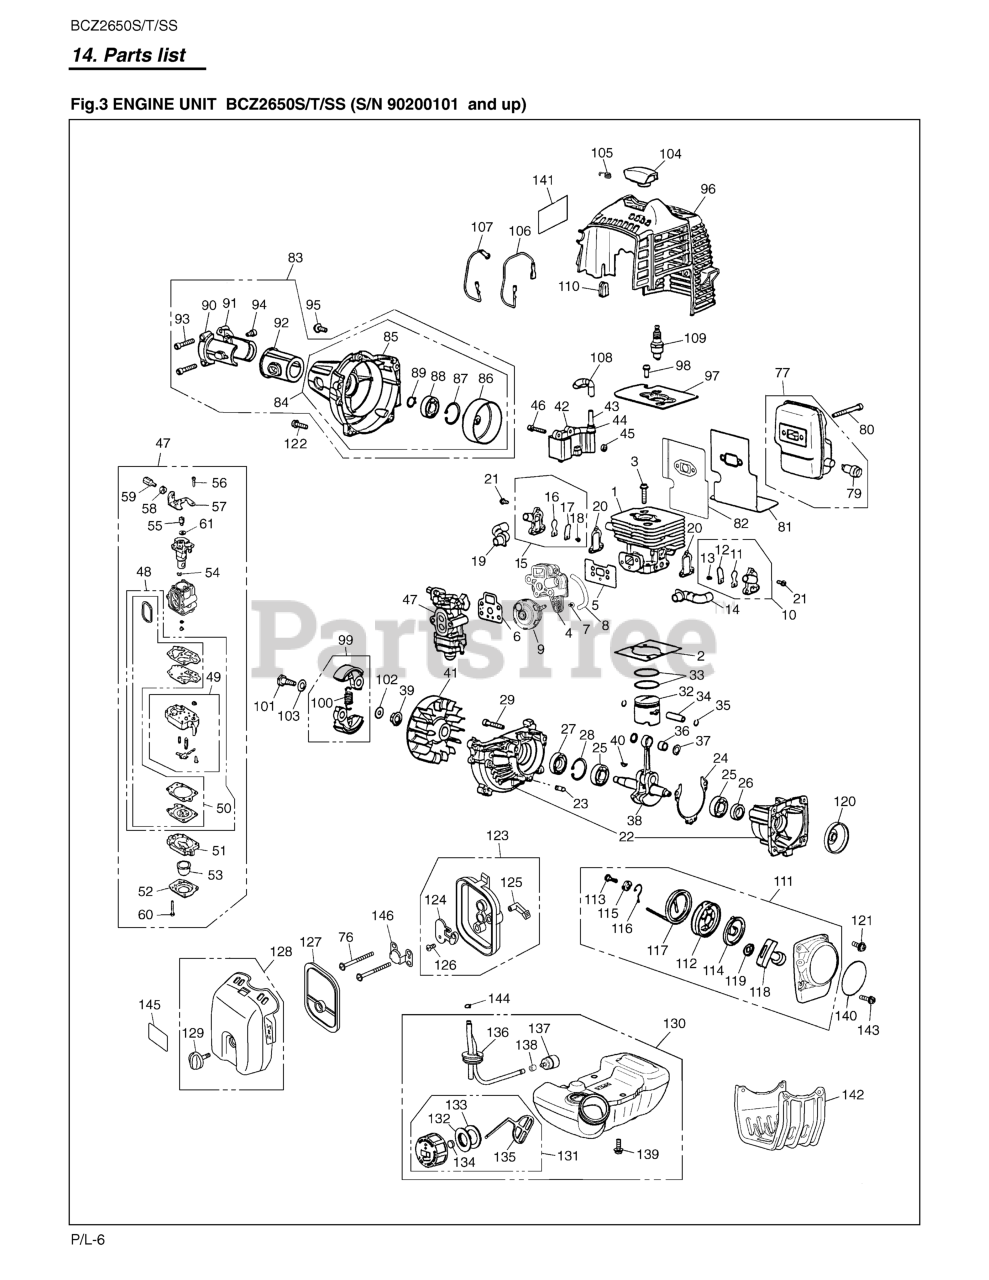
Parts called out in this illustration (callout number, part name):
1	CYLINDER
2	GASKET
3	BOLT
4	INSULATOR
5	GASKET
6	GASKET
7	SCREW
8	TUBE
9	PUMP ASSY
10	REEDVALVE (S) ASSY
11	REEDVALVE
12	STOPPER
13	SCREW
14	PIPE, AIR S
15	REED VALVE ASSY-F
16	REEDVALVE
17	STOPPER
18	SCREW
19	PIPE, AIR F
20	GASKET
21	SCREW
22	CRANKCASE COMP
23	PIN
24	GASKET
25	BEARING
26	SEAL
27	SEAL
28	RING
29	BOLT
32	PISTON
33	RING
34	PIN
35	RING
36	BEARING
37	WASHER
38	CRANKSHAFT COMP
39	NUT
40	KEY
41	ROTOR
42	COIL ASSY
43	CORD
44	CAP
45	SPACER
46	BOLT TORX
47	CARBURETOR ASSY
48	REBUILD KIT
49	BODY ASSY
50	GASKET KIT
51	BODY
52	COVER
53	PUMP
54	RING
55	SWIVEL
56	SCREW
58	NUT
59	SCREW
60	SCREW
61	WASHER
76	BOLT
77	MUFFLER ASSY
79	ARRESTER
80	BOLT
81	GASKET
82	PLATE
83	COVER ASSY
84	COVER COMP
85	COVER FAN
86	DRUM
87	RING
88	BEARING
89	RING
90	BRACKET-A
91	BRACKET-B
92	CUSHION
93	BOLT
94	BOLT
95	BOLT, TORX
96	COVER, ENGINE
97	PLATE
98	BOLT
99	SHOE
100	SPRING
101	SCREW
102	WASHER
103	WASHER
104	CAP
105	SPRING
106	CORD
107	CORD
108	TUBE
109	SPARK PLUG
110	GROMMET
111	RECOIL ASSEMBLY
112	REEL
113	SCREW
114	SPRING
115	COLLAR
116	ARM
117	ROPE
118	KNOB
119	PLATE, STOPPER
120	PULLEY
121	BOLT
122	BOLT
123	BODY, CLEANER
124	PLATE, CHOKE
125	LEVER
126	SCREW
127	ELEMENT
128	CLEANER COVER ASSY
129	CLEANER KNOB
130	TANK ASSY
131	CAP ASSY
132	HOLDER ASSY
133	PACKING
134	FILTER
135	STOPPER
136	PIPE COMP
138	CLIP
139	SCREW
140	LABEL, RECOIL
141	LABEL, EMISSION
142	GUARD
143	BOLT
144	CLIP
